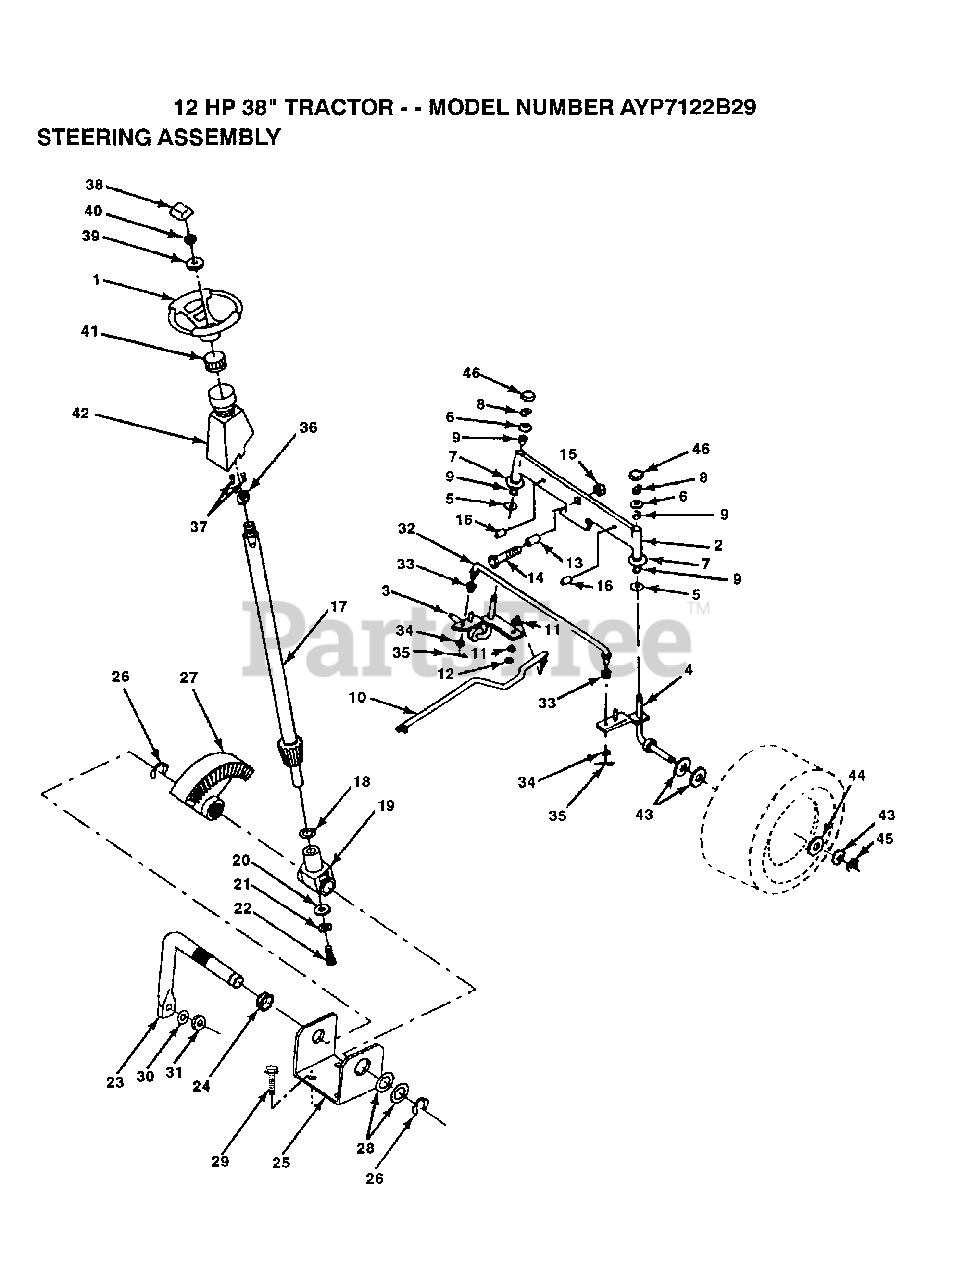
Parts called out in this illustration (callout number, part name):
3	SPINDLE LH
4	SPINDLE RH
5	WASHER .T
6	WASHER
7	WASHER
8	RING
9	COL. SRTG. BEAR.
11	LOCKWASHER
13	BEARING
14	BOLT HEX 5/8-11
16	AXLE PIN
17	SHAFT ASM
18	THRUST WASHER
19	SUPPORT.SHAFT
21	LOCKWASHER
22	"SCREW,SPECIAL"
24	NYLINER T
25	"BRKT,STEERING"
26	RING
28	WASHER .T
29	SCREW
30	LOCKWASHER
32	TIE ROD
33	BUSHING.DRAGLINK
34	WASHER
35	COTTER PIN
38	ST WHL INSERT CAP
39	WASHER T
40	GRIPCO NUT
41	ADAPTER-WHEEL LT
42	"TUBE, STR SHAFT"
43	WASHER
44	WASHER
45	RING
46	CAP
